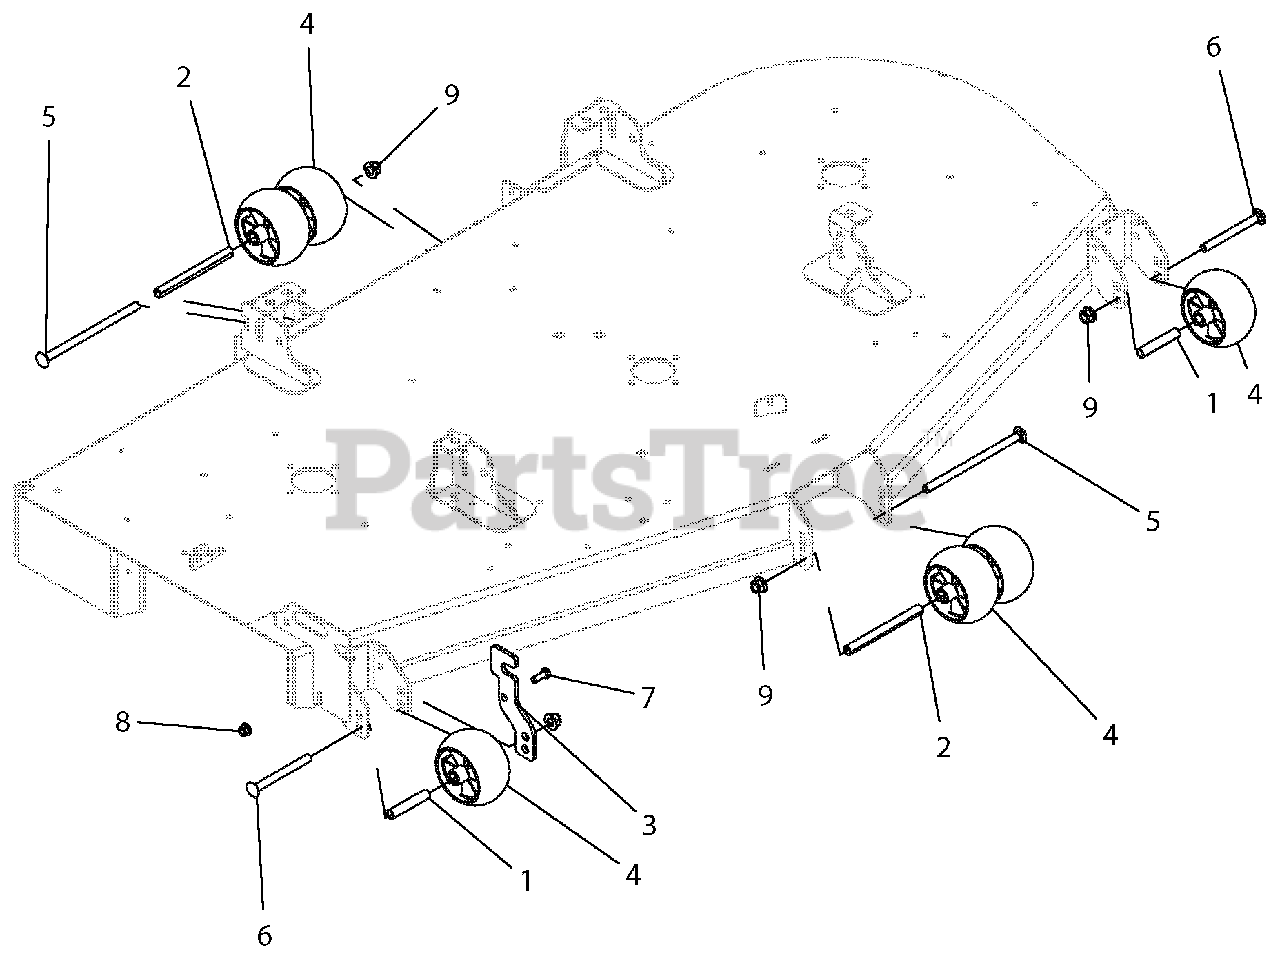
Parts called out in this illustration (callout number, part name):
1	SPACER, .510X.625X3.35
2	SPACER, .510X.625X6.70
3	CHUTE STORAGE BRACKET-RED
4	ANTI-SCALP WHEEL - 5X3 CTR
5	BLT-RDHDSQNK .50-13X8.50 Y
6	BLT-RDHDSQNK .50-13X5.00 G5 YWZC
7	BLT-HEX .38-16X1.00 GR5 YWZC
8	NUT-LK-NYL-FLG .38-16 YWZC
9	NUT-LK-NYL-FLG .50-13 YWZC
